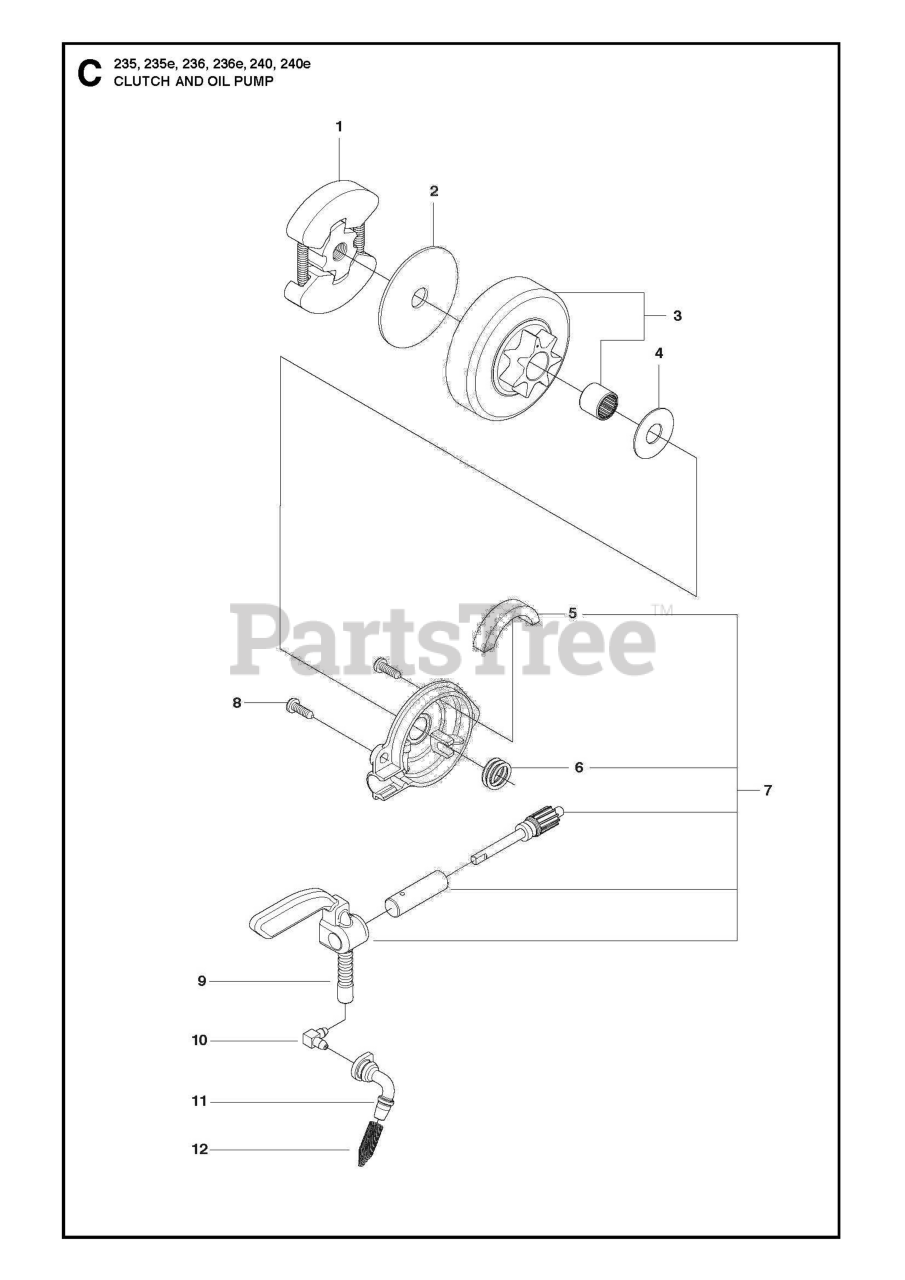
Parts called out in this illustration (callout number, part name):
1	CLUTCH ASSEMBLY
2	FRICTION DISC,CLUTCH 36/41
3	CLUTCH DRUM ASSY
3	ASSY CLUTCH DRUM .325"
7	OIL PUMP ASSY
8	SCREW
11	SEAL PICKUP
12	SCREEN/FILTER
